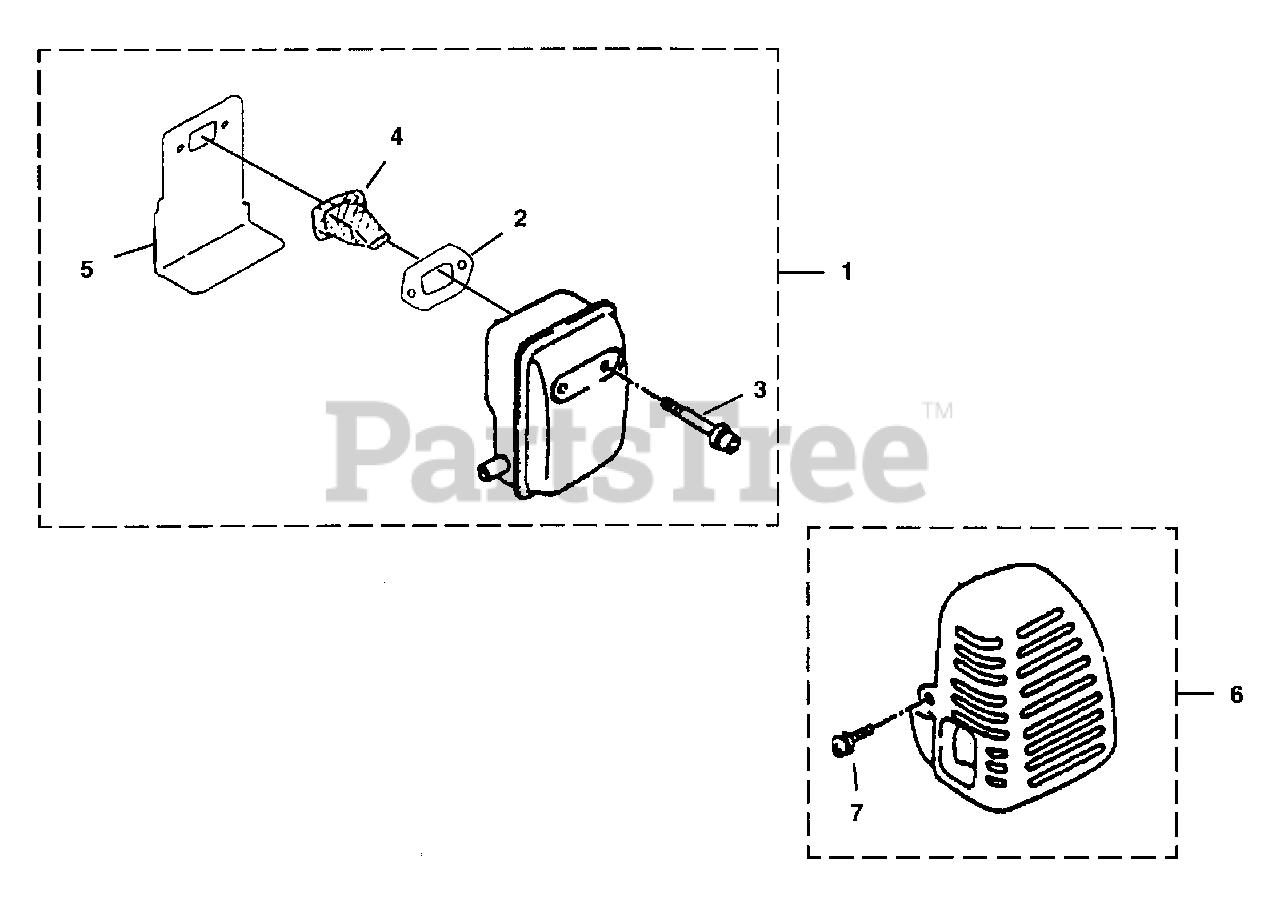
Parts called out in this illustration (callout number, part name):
1	MUFFLER ASSEMBLY
2	GASKET-Muffler
3	SCREW-Socket Hd. (M5 x 55)
4	SPARK ARRESTOR
5	GASKET-Muffler
6	MUFFLER COVER (Black)
7	SCREW ASSEMBLY (M5 x 14)
